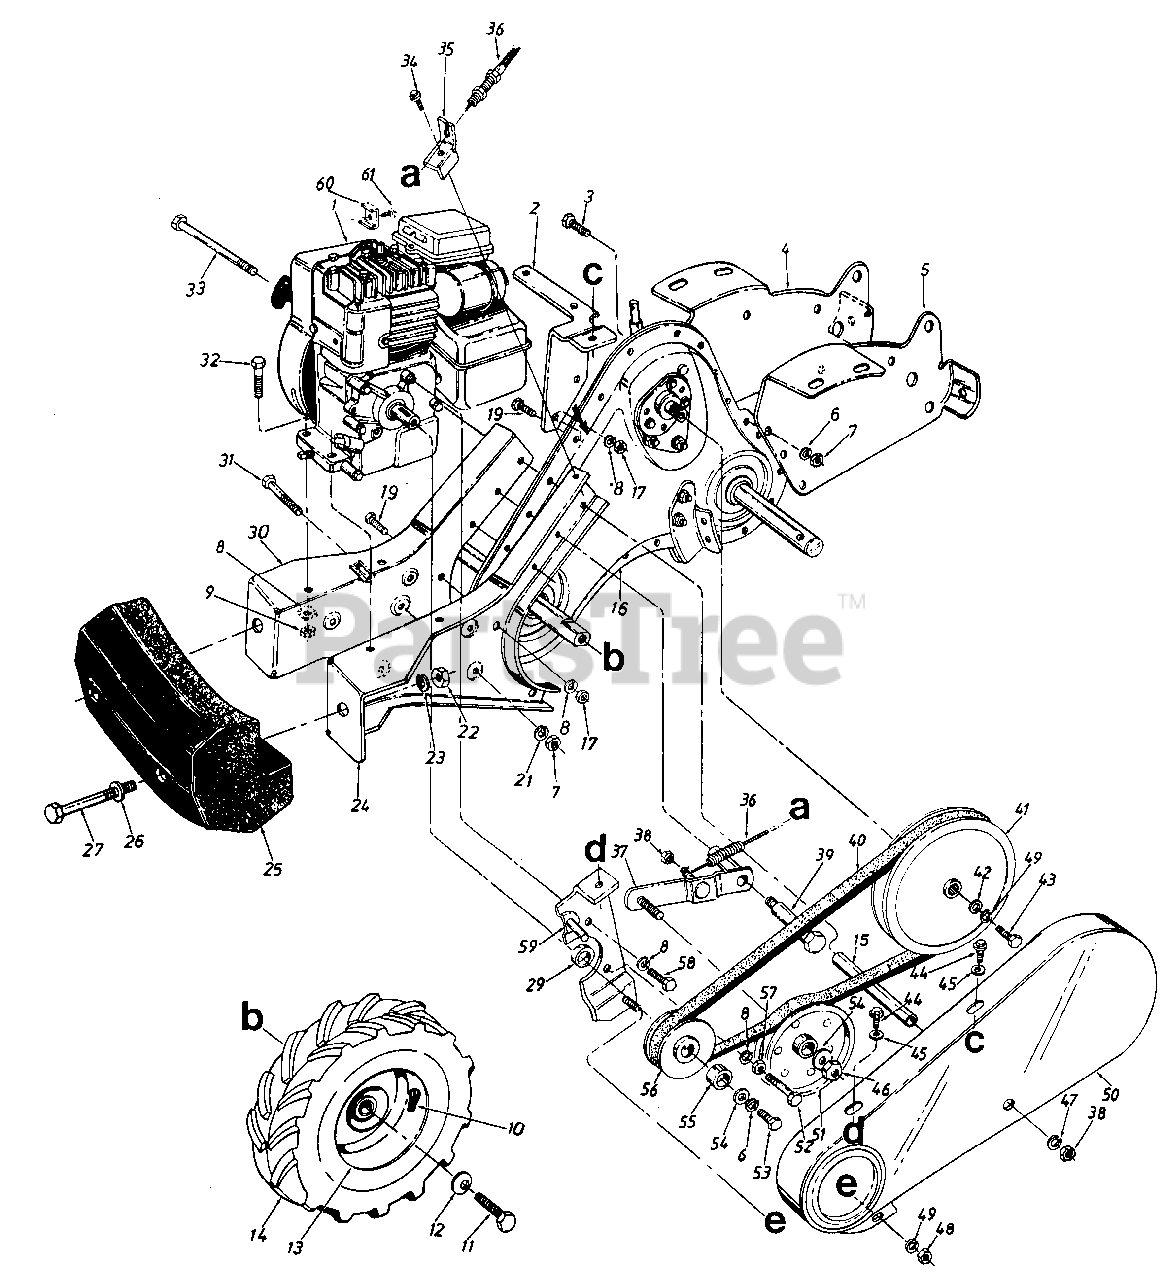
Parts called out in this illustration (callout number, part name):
2	BRACKET-MTG
3	SCREW-HEX 3/8-16 X 1.00
7	NUT-HEX 3/8-16
8	WASHER-LOCK-5/16
9	NUT-HEX 5/16-18
10	VALVE-TUBELESS AIR
11	SCREW-HEX 5/16-24 X .62
12	WASHER-BELL .337 X .867 X .057
13	WHEEL RIM
14	WHEEL ASSY W/TIRE-LH
16	GEAR CASE ASSY
17	NUT-HEX 5/16-18
18	SCREW-HEX 5/16-18 X .75
19	WASHER-HDL 3/8
21	WASHER-HDL 3/8
22	NUT-HEX 1/2-13
23	WASHER-LOCK-1/2
26	WASHER-FL
27	BOLT-HEX 1/2-13X5.0
32	SCREW-HEX 5/16-18 X 1.50
33	SCREW-HEX
34	SCREW-HEX WASH HD 5/16-18
36	CABLE-CLUTCH CONTROL
39	SCREW-SHLD
40	BELT-V 1/2 X 57.0
42	WASHER-FL
43	SCREW-HEX 1/4-28 X .75
44	SCREW-HEX WASH SF TAPP
45	WASHER-FL
46	NUT-HEX CENTER JAM 3/8-24
47	WASHER-FL-.344 ID X 1.12 OD X .063
48	NUT-HEX 1/4-20
49	LOCK WASHER 1/4 DIA
51	PULLEY-IDLER
52	SCREW-HEX 5/16-24 X 1.75
53	BOLT-3/8 NF X 1"GR5
54	WASHER-FL-.385 X 1.00 X .135
56	PULLEY HALF-ENGINE
57	NUT-5/16-24
58	SCREW-HEX 5/16-24 X .62
61	SCREW-HEX SEMS #10-32
